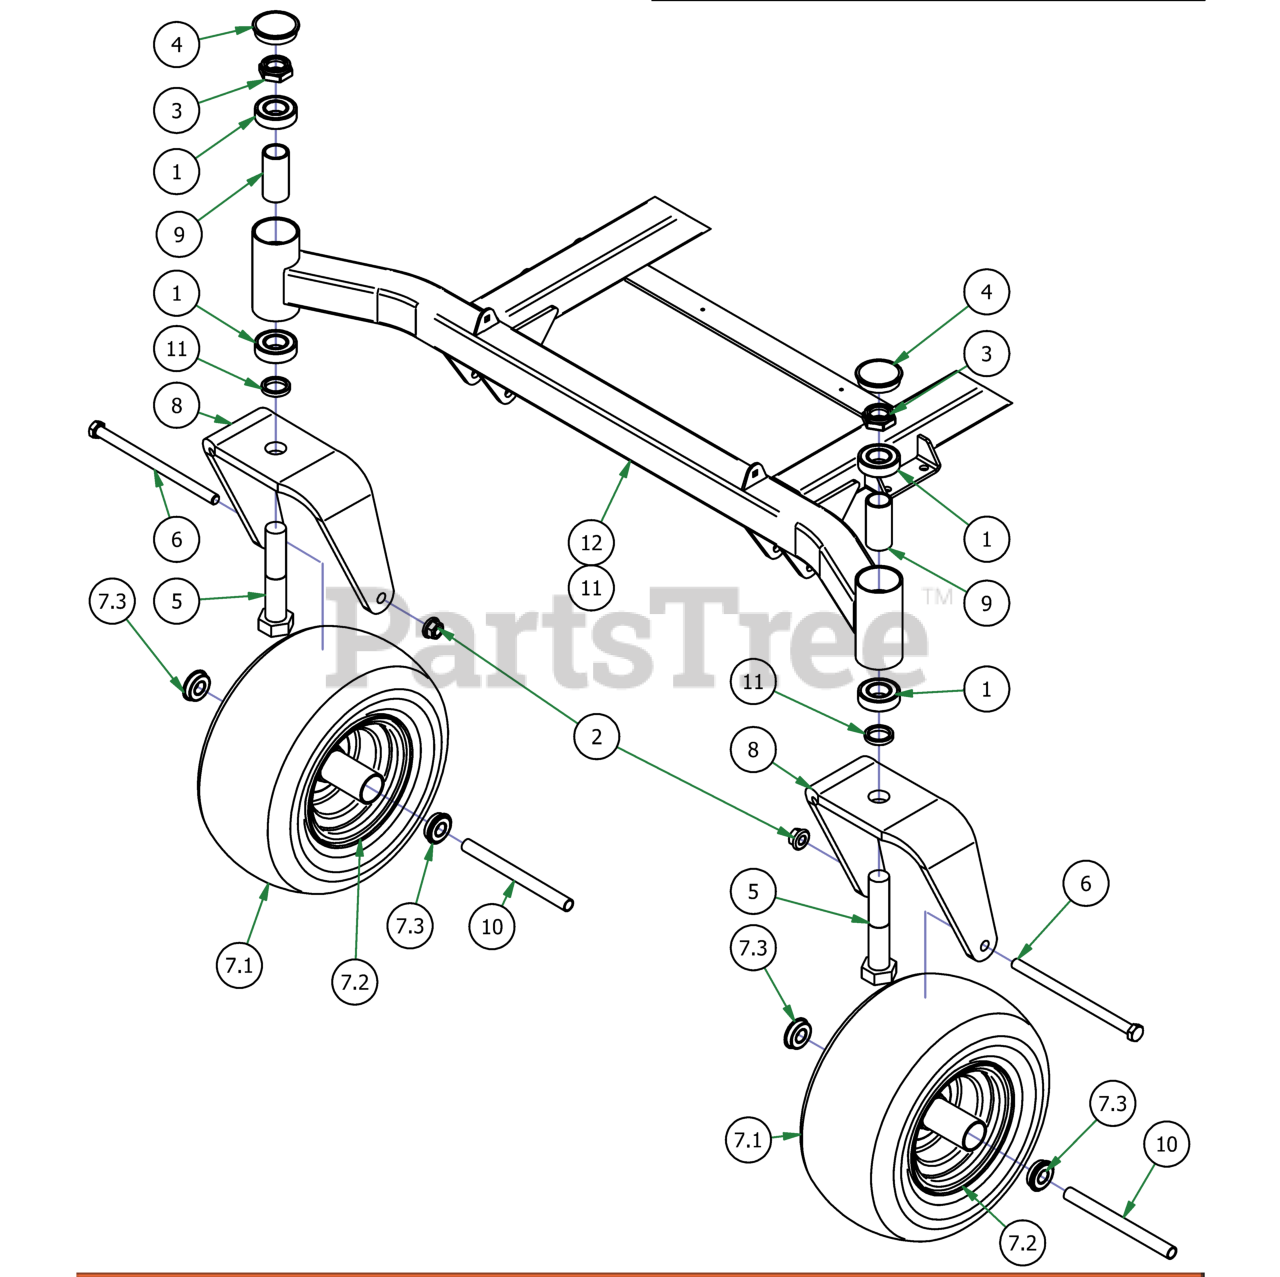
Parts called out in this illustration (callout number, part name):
1	1641 BEARING W/2 CONTACT RUBBER SEALS
2	1/2-13 NYLON INSERT FLANGE LOCKNUT ZINC
3	1" Fine Thread 1/2 Nylock Nut
4	2017 Bearing Cover
5	1-14 x 5 Hex Bolt Grade 8 Zinc Yellow
6	1/2" x 8 1/2 GR 5 Hex Bolt
7	12x6-6 Black Tire and Wheel Assembly
7.1	12 x 6 - 6 Front Tire
7.2	Front Tire Rim
7.3	Ball Bearing w/Retainer, 99502H-NR, .625 Bore x 1.375 OD x .4375 Width
8	2017 ZT Front Fork
9	2016 Front Bearing Spacer
10	Front Wheel Spanner
11	Spacer, 1x1.375x.25
12	2017 MZ/ZT 54"-60" Frame
